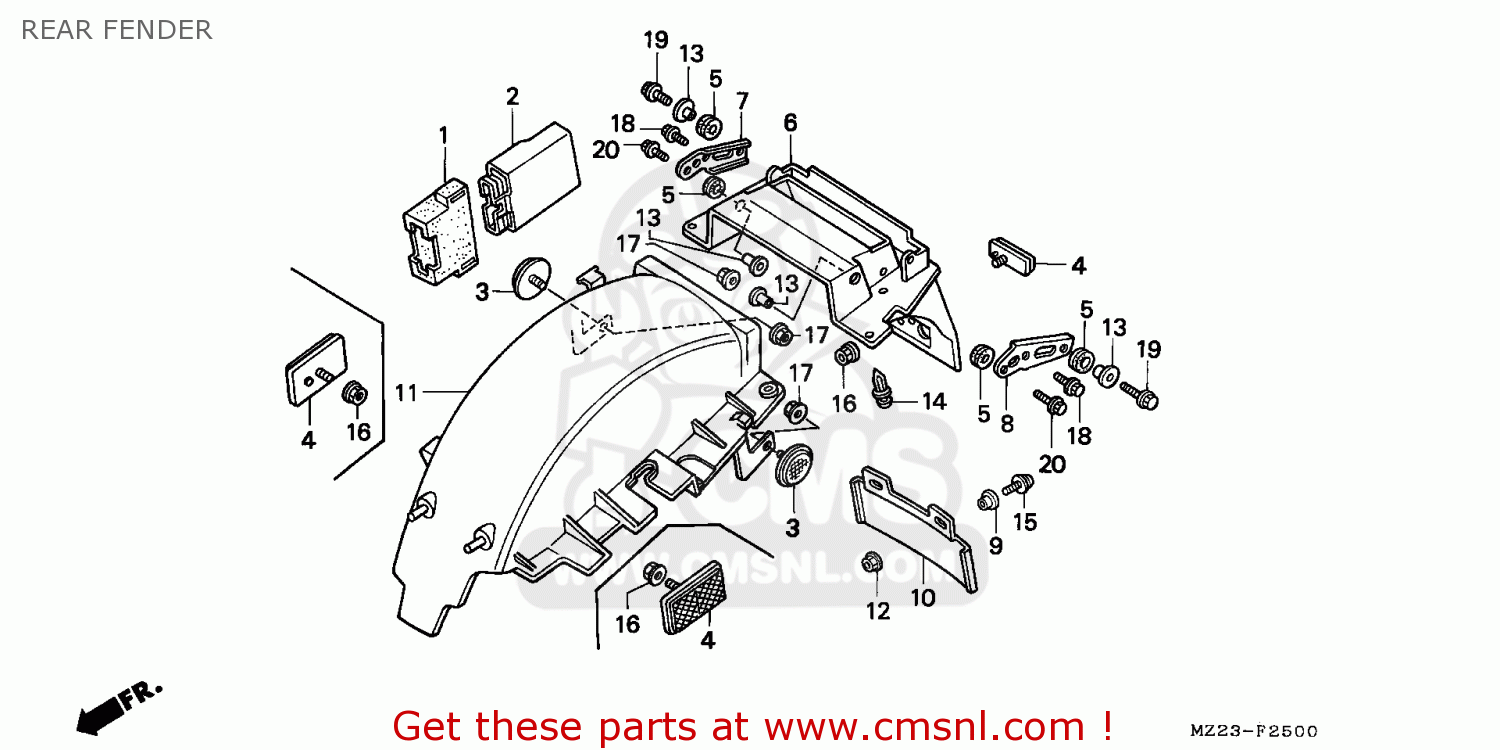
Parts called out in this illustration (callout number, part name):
1	CUSHION,SPARK UNI
2	UNIT COMP,SPARK
4	REFLECTOR,REFLEX
5	RUBB,LIGHT MOUNT
6	FENDER A,RR
7	STAY,R.RR.FENDER
8	STAY,L.RR.FENDER
11	FENDER COMP.(B)
13	COLLAR,FR.FENDER
14	CLIP,BODY COVER
16	NUT,FLANGE,5MM
20	BOLT,FLANGE,6X25
